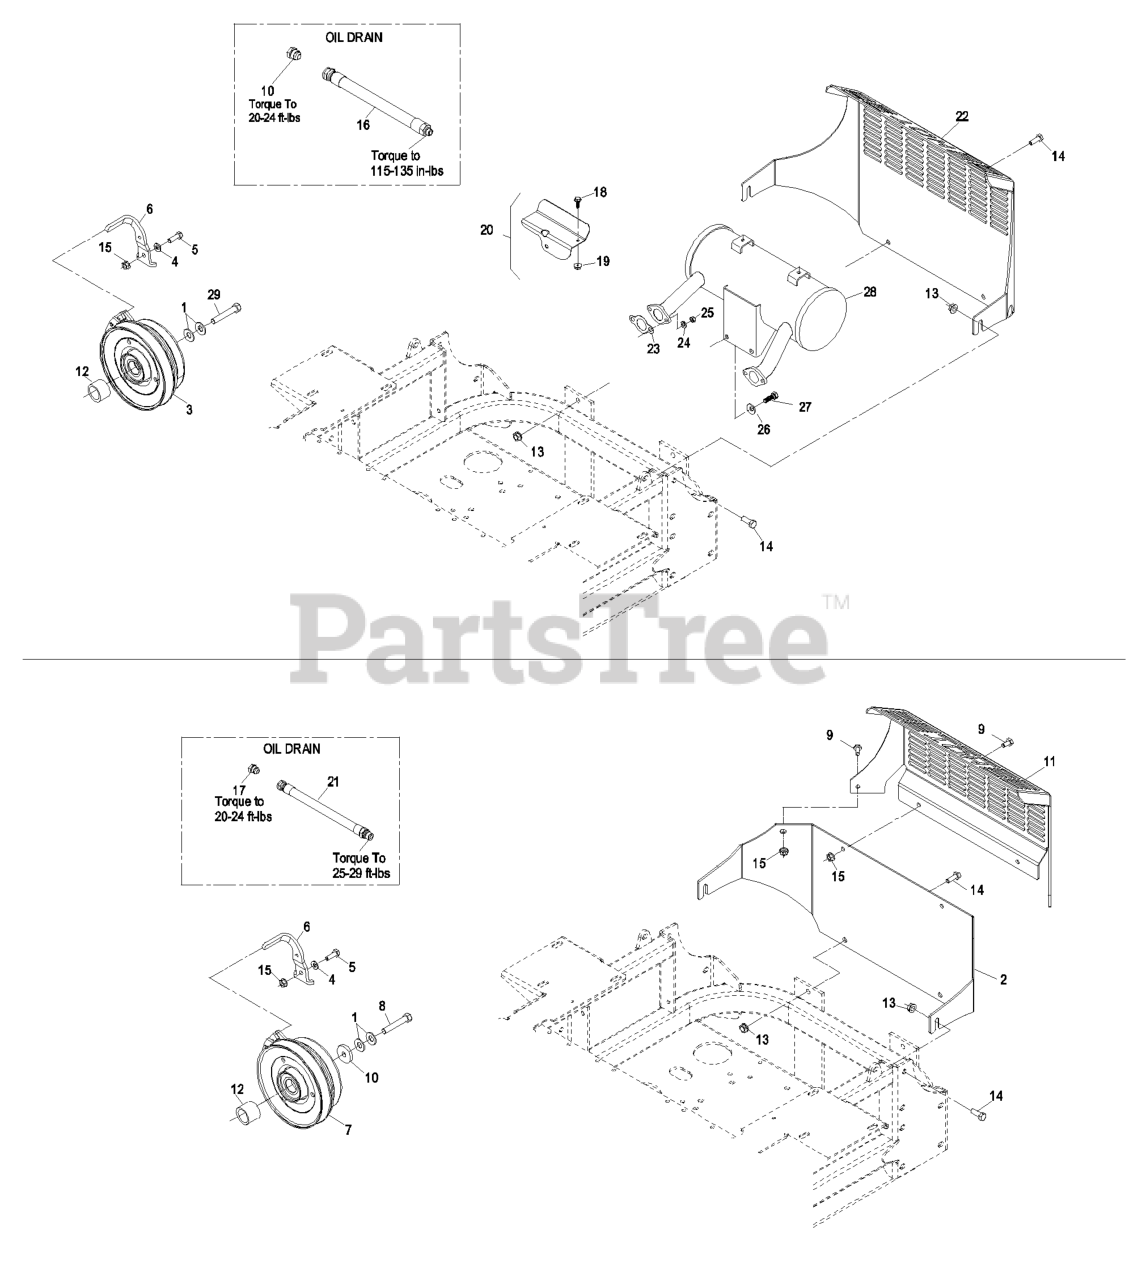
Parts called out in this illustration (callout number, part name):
1	WASHER-SPRING
2	GUARD,CLUTCH
3	KIT,SPOT BRAKE CLUTCH 1.1
4	WASHER-SPRING
5	SCREW-HH
6	ANCHOR-CLUTCH
7	SPOT BRAKE CLUTCH KIT
8	SCREW-HH
9	SCREW-HH
10	KEEPER-CLUTCH
11	GUARD,MUFFLER
12	SPACER-CLUTCH
13	NUT-HHF, WHIZ
14	SCREW-HH
15	NUT-HF
18	SCREW-HH
20	CABLE HEAT SHIELD KIT
22	GUARD, REAR KC
24	WASHER-LOCK
25	NUT-HEX
26	SCREW-HH
27	SCREW-HH
28	KIT,MUFFLER KOHLER
29	SCREW-HH
